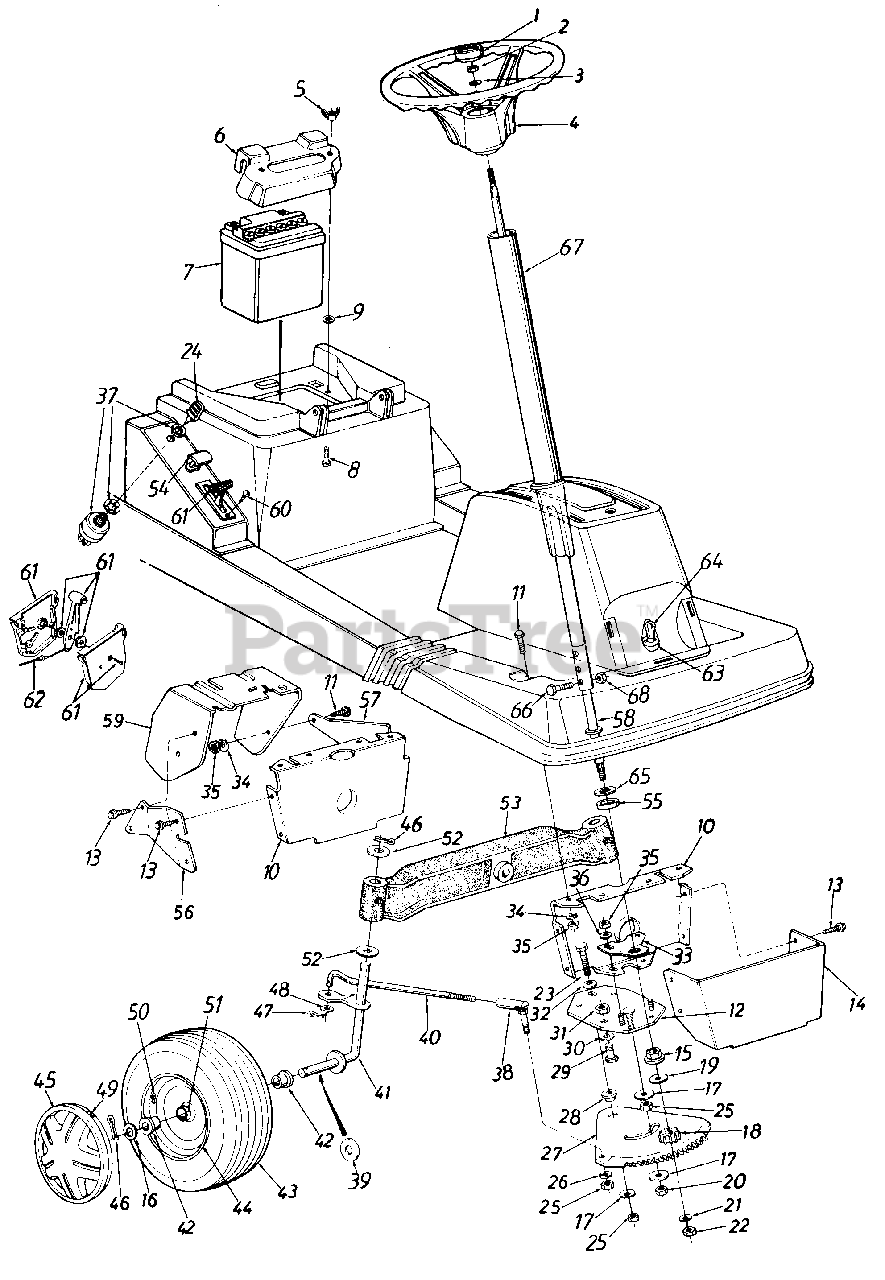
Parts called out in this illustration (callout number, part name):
1	Steering Wheel Cap
2	Hex L-Nut 5/16-24 Thd.
3	Bell-Wash. .345" I.D. x .88" O.D.
4	Steering Wheel Ass'y.
5	Wing Nut 1/4-20 Thd.
6	Battery Hold Down Cover
7	12V Battery
8	Hex Bolt 1/4-20 x 1.75" Lg.
9	Push On Retaining Ring
16	Fl-Wash. .635" I.D. x 1.585"
17	Fl-Wash. .385" x 1.37" O.D.
18	Steering Pinion Gear
19	Fl-Wash. .510" I.D. x 1.0" O.D.
20	Hex L-Nut 3/8-24 Thd.
21	Fl-Wash. .34" I.D. x .68" O.D.
22	Hex Nut 5/16-24 Thd.
23	Hex Bolt 3/8-24 x 1.5" Lg. (Gr. 5)
24	Ignition Key
25	Hex Nut 3/8-24 Thd.
26	L-Wash. 318" I.D.
27	Steering Gear Segment
28	Shld. Spacer
29	Hex Bolt (Nylon) 1/2-13 x .75" Lg.
30	Fl-Wash. .53" I.D. x .93" O.D.
31	Hex Nut 1/2-13 Thd.
32	Bell-Wash. .385" I.D. x .88"
33	Steering Gear Adjuster
34	L-Wash. 5/16" I.D.
35	Hex Nut 5/16-18 Thd.
36	Spr. Wash. .32" I.D. x .62" O.D.
37	Ignition Switch
38	Ball Joint Ass'y.
39	Fl-Wash. .64" I.D. x 1.24" O.D.
40	Steering Tie Rod
41	Front Axle Ass'y.-R.H.
42	Flange Bearing (Bronze)
43	Wheel Ass'y. Comp.
45	Hub Cap
46	Cotter Pin 1/8" Dia. x 1.25" Lg.
47	Cotter Pin 1/8" Dia. x 1.0" Lg.
48	Fl-Wash. .385" I.D. x .87" O.D.
49	Spring Clip
50	Air Valve
51	Grease Fitting
52	Fl-Wash. .76" I.D. x 1.49" O.D.
55	Spacer .985" I.D. x 1.25"
59	Clutch Pedal Brkt. Ass'y.
60	Truss Mach. AB-Tap Scr. #10 x .5" Lg.
61	Throttle Control Box Ass'y.
62	Throttle Control Wire 39" Lg.
63	Headlight Socket
64	Lamp
65	Fl-Wash. .64" I.D. x 1.24"
66	Hex Bolt 1/4-20 x 1.25" Lg.
67	Steering Shaft Ass'y.
68	Hex L-Nut 1/4-20 Thd.
